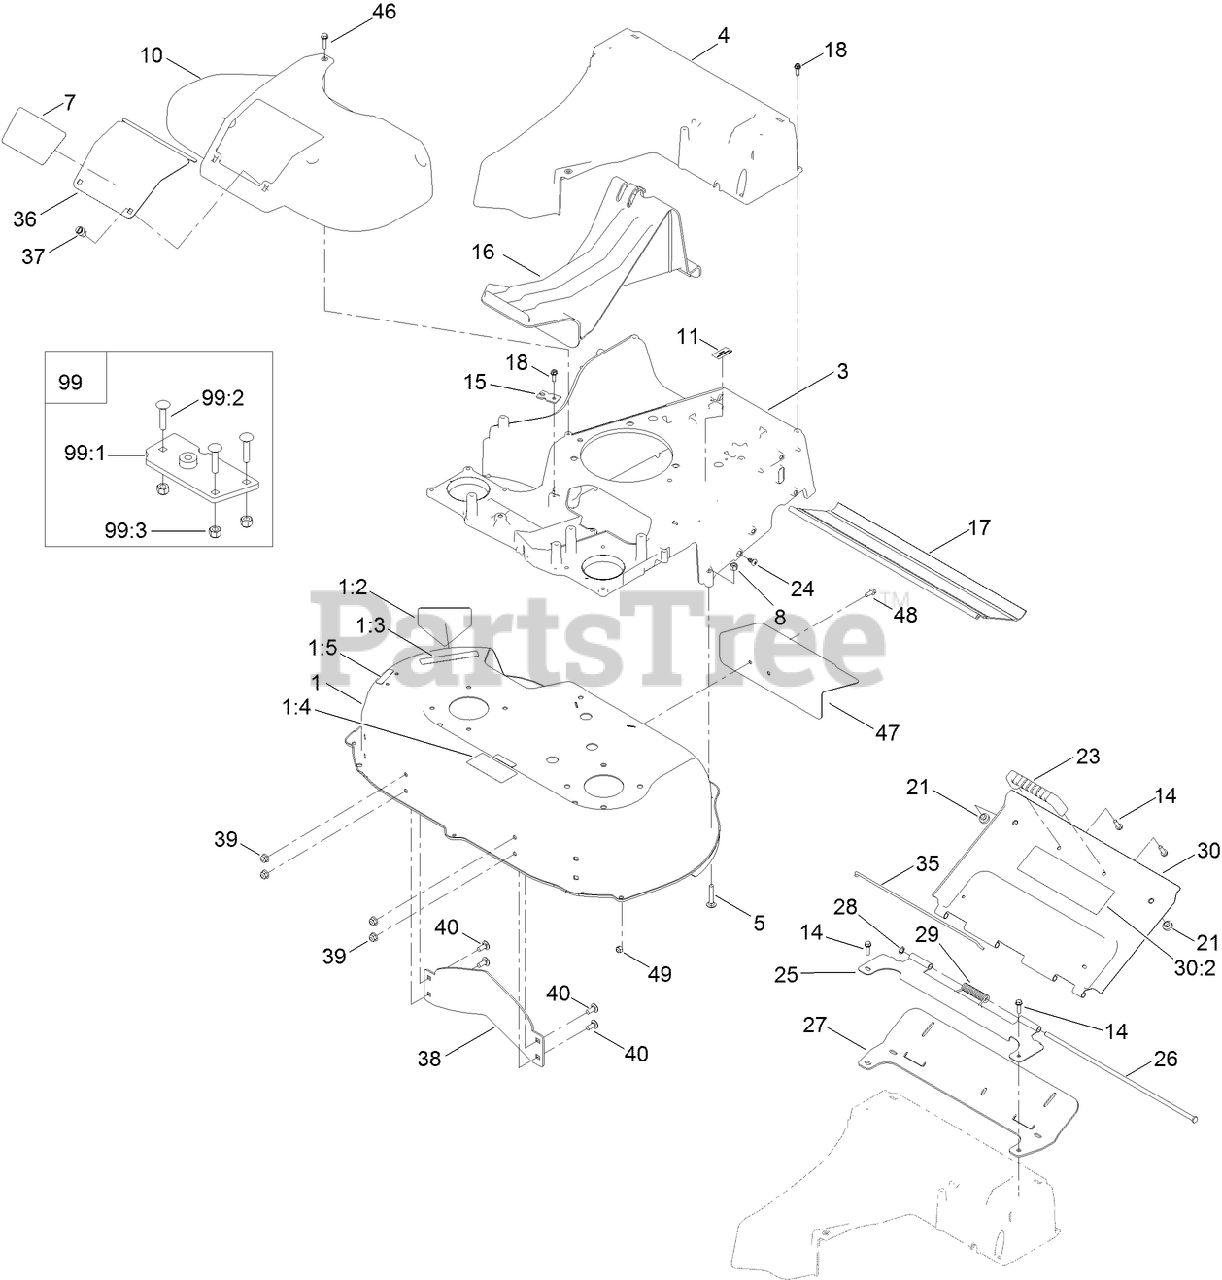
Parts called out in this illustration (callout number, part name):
1	DECK ASM
1:2	DECAL-DANGER
1:3	DECAL-DANGER
1:5	DECAL-WARNING
3	FRAME
5	BOLT-CAR
8	NUT-LOCK, NI
10	COVER-BELT
11	DECAL-PATENT
14	SCREW-HWH
15	BRACKET-CABLE, TRACTION
16	PLUG-MULCH
17	SHIELD-TRAILING
18	SCREW-HWHTF
21	BUMPER
23	HANDLE-DOOR
24	SCREW-PTH
25	BRACKET-HINGE
26	PIN-HINGE
27	SEAL-DOOR
28	RING-RETAINING
29	SPRING-TORSION, COVER
30	REAR DOOR ASM
30:2	DECAL-WARNING
35	CLIP-SEAL
36	DOOR-ACCESS
37	FASTENER
38	BAFFLE-CONTROL
39	NUT-HF, NI
40	SCREW-CARR
46	SCREW-HWHTF
47	DEFLECTOR-REAR
48	SCREW-HWH
49	NUT-LOCK, NI
99	FRAME PLATE KIT
99:1	PLATE-FRAME
99:2	SCREW-CARR
99:3	NUT-LOCK, NI
